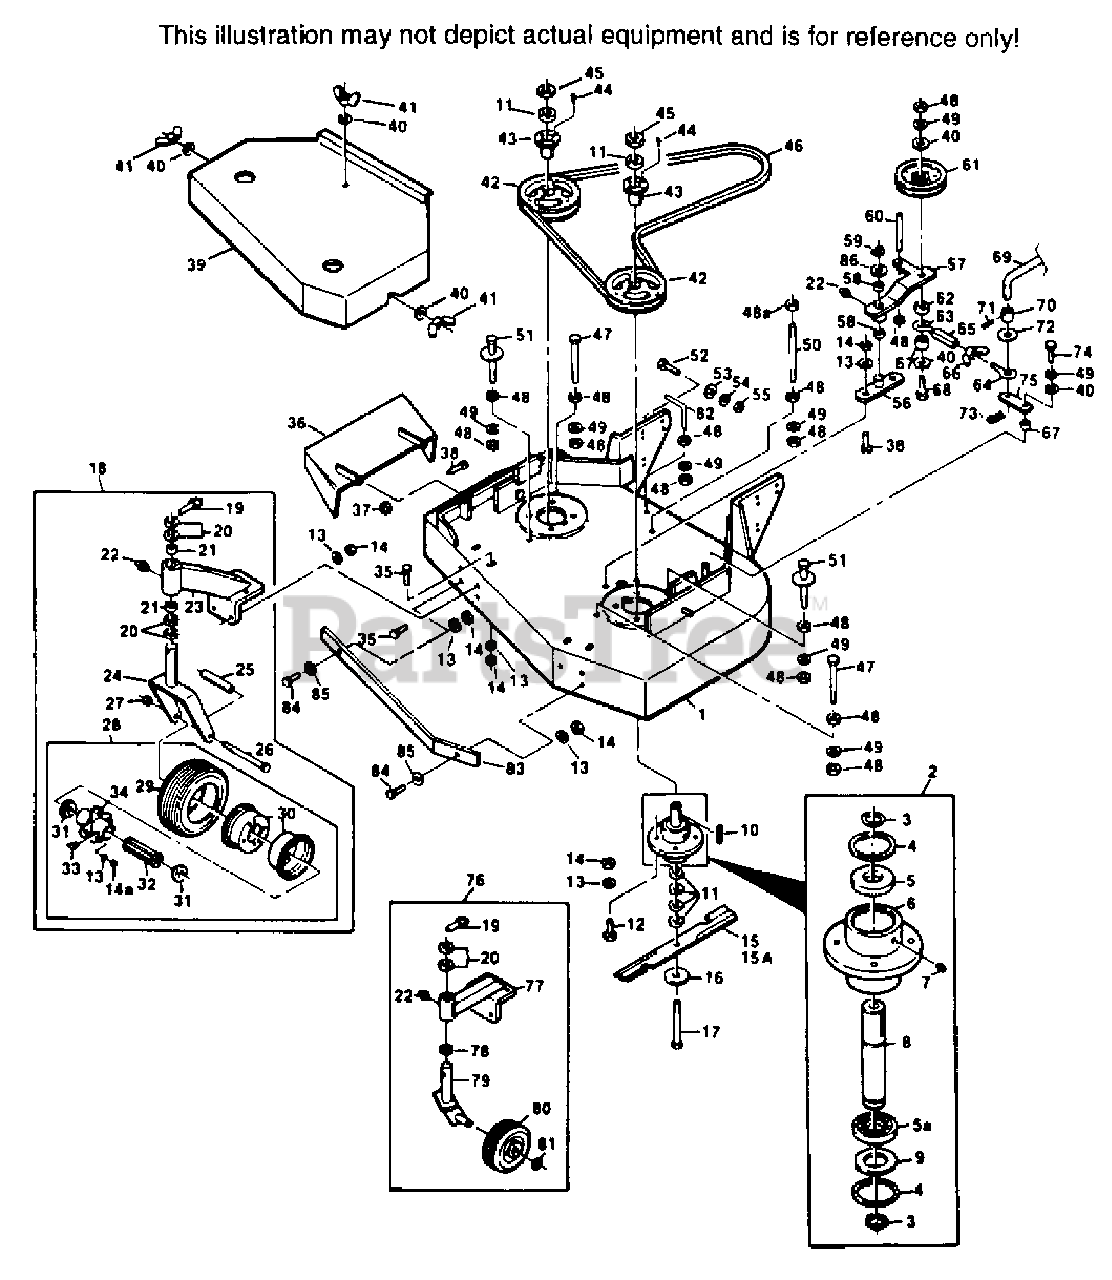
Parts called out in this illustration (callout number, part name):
2	CUTTER SPINDLE ASSY(INCL 3-9)
3	RETAINING RING, 1"EXT.-INVERTED
4	RETAINING RING, 2-7/16 INT.BSC
5	BEARING CUTTER SPINDLE UPPER
5A	BEARING CUTTER SPINDLE LOWER
6	SPINDLE HOUSING
7	GREASE FITTING, STR 5/16 SERR
8	SPINDLE, CUTTER BLADE
9	WASHER, 1-5/16 X 2-13/32 X 16 GA.
10	KEY, 1/4 X 1/4 X 2
11	SPACER, CUTTER BLADE
16	FLAT WASHER, 5/8 W
17	HEX HD BOLT, 5/8-11 X 9-1/2
19	QUICK PIN
20	SPACER, CASTER YOKE, 1/2" LONG
22	GREASE FITTING, STR. 1/4-28
36	DISCHARGE CHUTE WLD
37	HEX NUT, 5/16-18 ELASTIC STOP
40	WASHER, 25/64 X 15/16 X 12 GA.
41	WING NUT, 3/8-16 ELASTIC STOP
42	PULLEY(INCL. 43-44)
43	TAPERED HUB
48A	HEX NUT, 3/8-16 CTR LOCKNUT
50	SUPPORT, BELT COVER
51	BELT GUIDE WLD
53	WASHER, 15/32 X 59/64 X 16 GA.
55	HEX NUT, 7/16-14 ELASTIC STOP
56	IDLER PIVOT WLD
57	IDLER ARM ASSY.(INCL. 22 & 58)
58	BRONZE BEARING
59	RETAINING RING, 3/4 EXT,-"E"
61	IDLER PULLEY, BELT CLUTCH
62	SPACER, IDLER
63	EYEBOLT, LH
64	EYEBOLT, RH
65	TURNBUCKLE
66	WING NUT, 5/16-18
67	SLEEVE, CLUTCH ROD
69	BLADE CLUTCH ROD, LOWER
70	SLEEVE, CLUTCH ROD
72	WASHER, 33/64 X 1 X 16 GA.
73	HAIR PIN, LARGE
75	CAM LINK
76	CASTER ASSY(INCL. 19-20, 22, 77-81)
77	CASTER SUPPORT WLD.
78	SPACER, CASTER YOKE, 1/4 LONG
79	CASTER YOKE WLD.
80	CASTER WHEEL ASSY.
81	RETAINING RING, 5/8 EXT.-E
82	BELT GUIDE
86	WASHER, 3/4 X 1 1/4 X .035
87	WASHER
